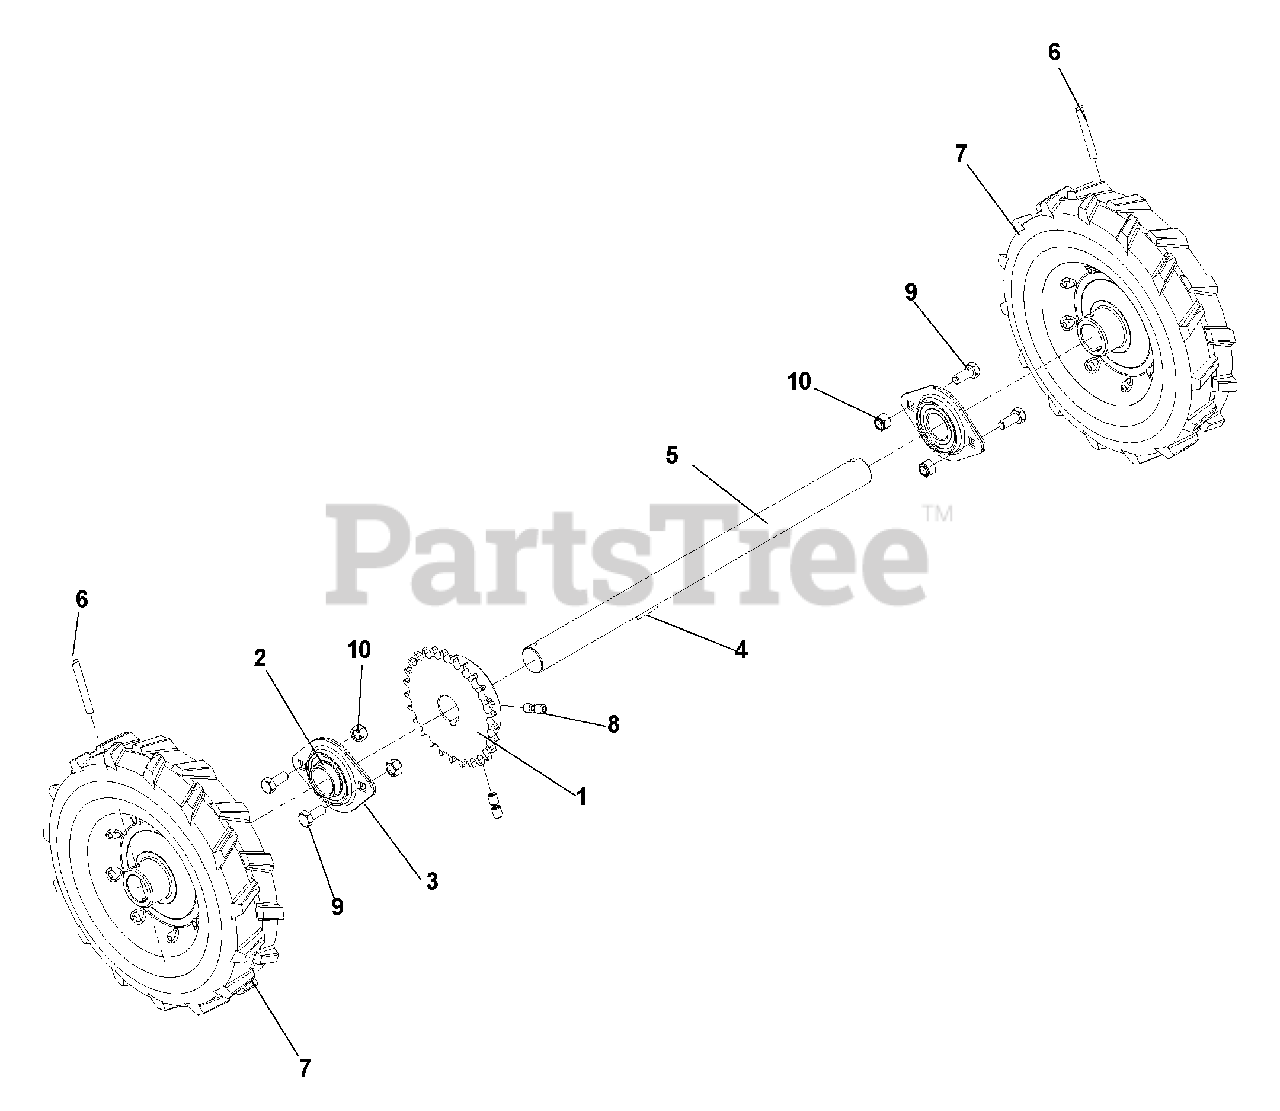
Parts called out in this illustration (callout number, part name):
1	SPROCKET, ROTOR
2	BEARING, 1" W/LOCKING COLLAR
3	FLANGE, BEARING
4	KEY, 1/4 SQ X 1
6	SPRIAL PIN, 1/4 X 1 1/2
8	SCREW, 5/16-18 X 3/8, SET
9	HCS, 5/16-18 X 3/4, GR5
10	NUT, 5/16-18, NYLOC
